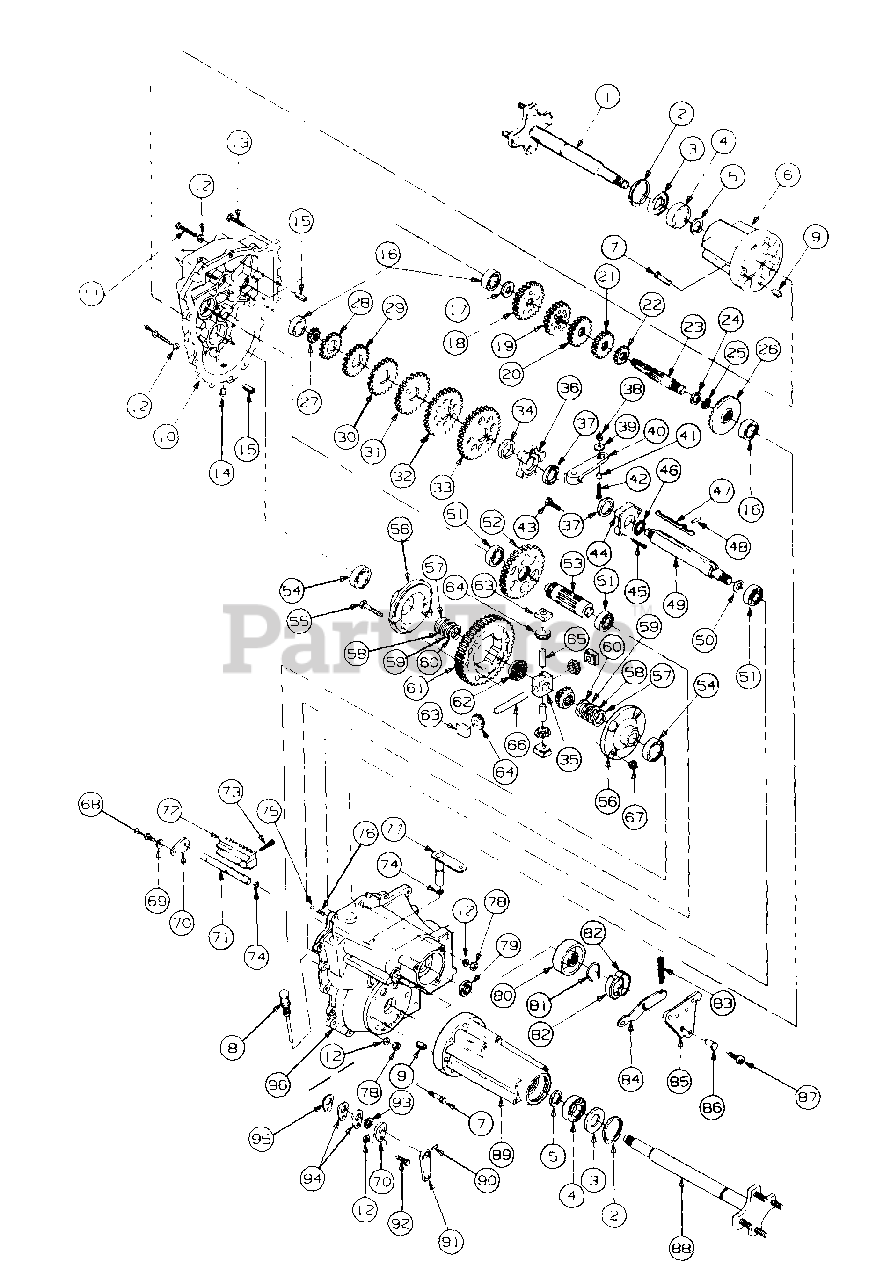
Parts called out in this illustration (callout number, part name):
1	Axle Assy, LH, 11.9" Lg
2	Ring, Inverted Retainer
3	Seal, Oil
4	Bearing
5	Ring, External Retaining
6	Housing, LH Axle
7	Screw, Hex L-Wash Tapp, 3/8-16 x 1.88
8	Dipstick, Oil
9	Bushing, Dowel
10	Housing, LH Differential
11	Screw, Hex Cap, 1/4-20 x 1.5
12	Washer, Flat, .25 x .62 x .052
13	Screw, Hex Wash Hd Tapp, 1/4-20 x 1.0
14	Plug, 1/2-14 NPTF
15	Pin, Slotted Spring, 7/16-1.0
16	Bearing, Ball
17	Washer, Flat, .68 x 1.25 x .060
18	Gear, 27T Drive, Sixth
19	Gear, 23T Drive, Fifth
20	Gear, 20T Drive, Fourth
21	Gear, 17T Drive, Third
22	Gear, 15T Drive, Second
23	Shaft, Drive w/First
24	Washer, Flat, .765 x 1.125 x .030
25	Washer, Wave, .79 x 1.125 x .012
26	Gear, 36T Bevel
27	Gear, 14T Reduction
28	Gear, 18T Shift, Sixth
29	Gear, 22T Shift, Fifth
30	Gear, 24T Shift, Fourth
31	Gear, 27T Shift, Third
32	Gear, 40T Shift, Second
33	Gear, 58T Shift, First
34	Spacer, Neutral
35	Block, Differential Pinion
36	Collar, Shift - LH
37	Spacer, Shift Key
38	Nut, Hex Center Lock, 5/16-18 GR5
39	Washer, Flat, .343 x .875 x .062
40	Arm, Key Shifter
41	Spacer, .316 ID x .44 OD x .263 Lg
42	Screw, Hex Cap, 5/16-18 x 1.0
43	Screw, Hex Cap, 5/16-18 x 1.25 GR5
44	Collar, Shift - RH
45	Screw, Socket Hd Cap, #10-32 x 1.25
46	Spring, Shift Key
47	Key, Shift
48	Pin, Dowel, 3/16 x 7/8 Lg
49	Shaft, Shift
50	Washer, Wave, .84 x 1.12 x .016
51	Bearing, Ball, .787 x 1.85 x .551
52	Gear, 44T Reduction
53	Shaft, 9T Output
54	Bearing, Ball
55	Screw, Hex Cap, 3/8-24 x 2.0
56	Cover, Differential
57	Washer, Flat, 1.0 x 1.56 x .010 Thk
58	Washer, Flat, 1.0 x 1.56 x .015 Thk
59	Washer, Flat, 1.0 x 1.56 x .020 Thk
60	Washer, Flat, 1.0 x 1.56 x .040 Thk
61	Gear, 60T Bull
62	Gear, 14T Differential Side
63	Block, Differential Thrust
64	Gear, 10T Differential Pinion
65	Shaft, Cross
66	Shaft, Cross, .50 OD x 3.485 Lg
67	Nut, Hex Lock, 3/8-24
68	Screw, Hex Wash Hd Tapp, 1/4-20 x .75
69	Washer, Bell, .265 x .75 x .062
70	Support, Interlock Shaft
71	Shaft, Interlock Shift
72	Interlock, Shift
73	Screw, Socket Hd Cap, 1/4-20 x 1.0
74	O-Ring, 1/2 ID x 5/8 OD
75	Ball, Detent, .250 Dia
76	Spring, Detent
77	Arm Assy, Shift
78	Nut, Hex Center Lock, 1/4-20
79	Seal, Shift Shaft
80	Drum, Brake
81	Spring, Brake
82	Shoe, Brake
83	Spring, Compression
84	Arm, Brake
85	Plate, Brake
86	Actuator, Brake Shoe
87	Screw, Low Hd Cap, 3/8-16 x .75
88	Axle Assy, RH, 15.6 Lg
89	Housing, Axle - RH
90	Pin, Spirol, 1/8 Dia x .812 Lg
91	Arm, Interlock Shift
92	Screw, Hex Wash Hd Tapp, 1/4-20 x .75
93	Ring, Retainer
94	Shim, Interlock Shaft Support, .030 Thk
95	Shim, Interlock Shaft Support, .015 Thk
96	Housing RH Differential
